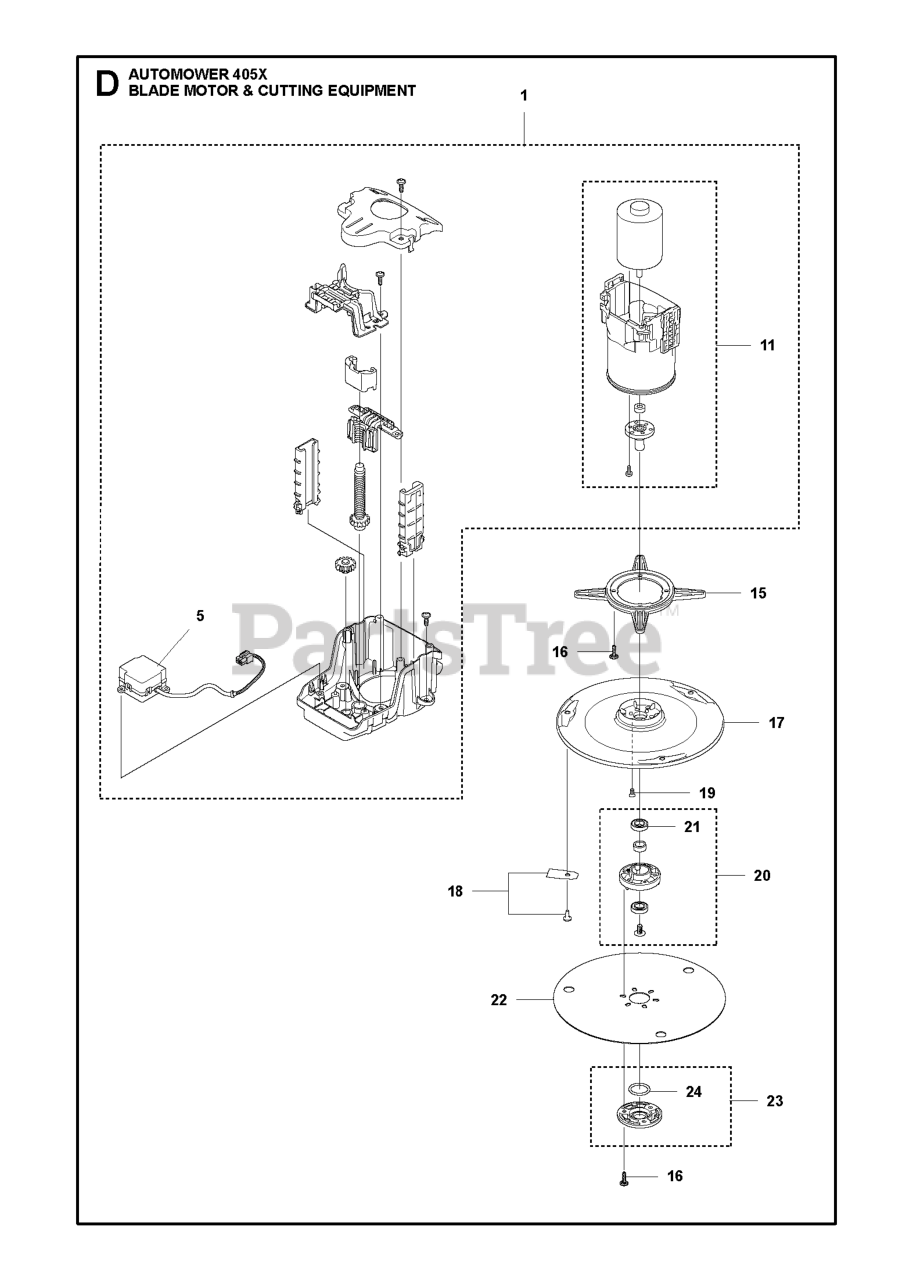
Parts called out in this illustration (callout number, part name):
1	CUTTING SYSTEM ECS TYPE 1
11	MOTOR ASSY CUTTING SYSTEM
15	FRAME MOTOR HOUSING
16	SCREW 14MM
17	GUARDS
19	SCREW HEXAGON SOCKET BUTTON HE
20	BEARING HOUSING ASSY
21	BALL BEARING BALL BEARING 535
21	BALL BEARING 2 RS,TIGHT CLEAR
23	COVER KIT BEARING
24	O-RING 20X2,5 MM
